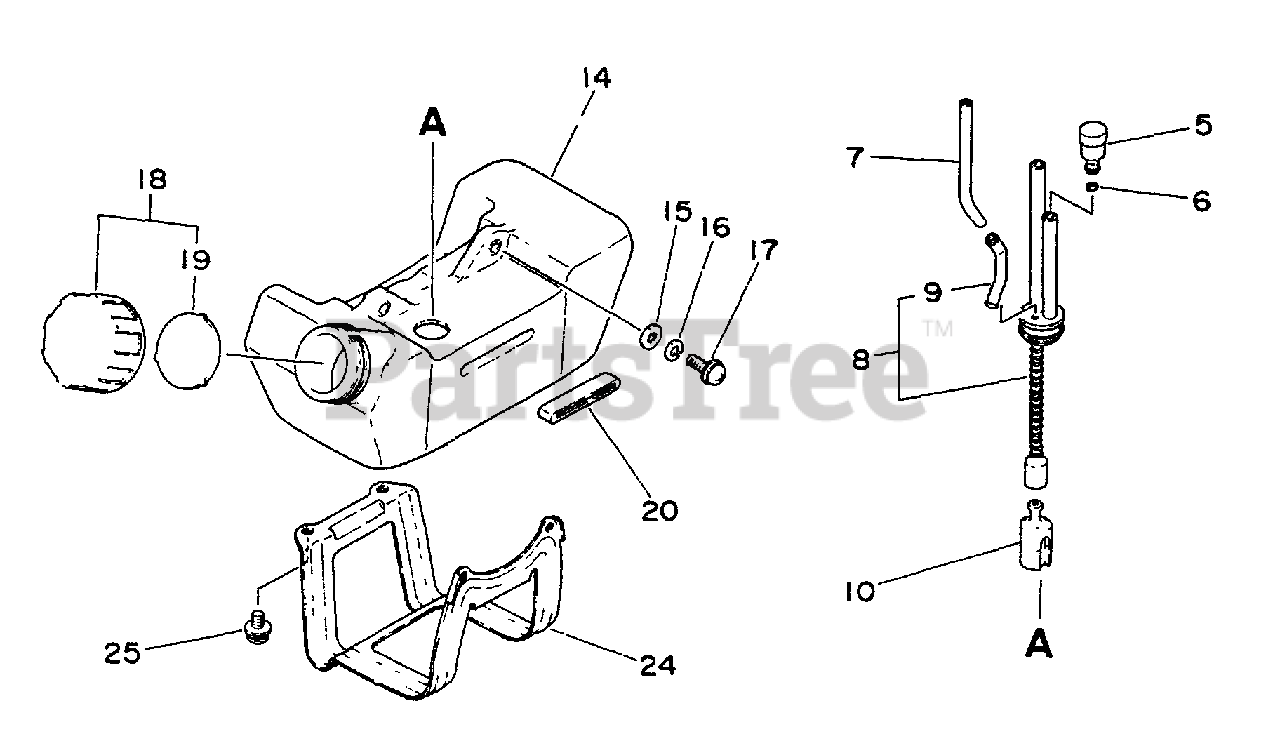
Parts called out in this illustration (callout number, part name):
5	VENT, FUEL TANK
6	CLIP - 5.5
7	PIPE - 3X6X75 -- CLEAR
8	FUEL PIPE KIT
9	CONNECTOR, PIPE
10	FILTER, FUEL
14	TANK, FUEL
15	WASHER - 5
16	LOCKWASHER - 5
17	SCREW - 5X16
18	CAP ASSY
19	GASKET, CAP
20	CUSHION, FUEL TANK
24	GUARD, FUEL TANK
25	SCREW - 5X10
